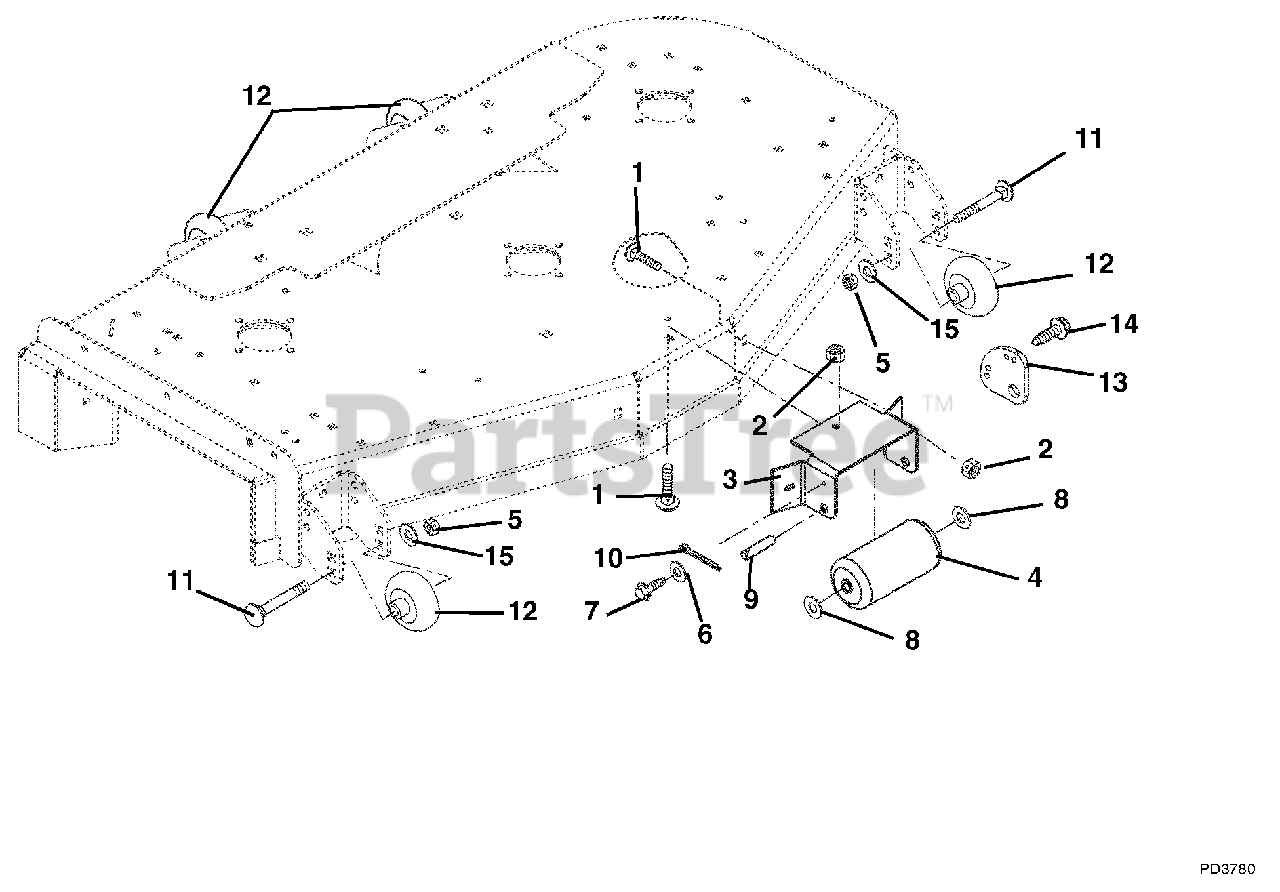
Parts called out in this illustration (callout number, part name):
1	Bolt-Round Head Square Neck .38-16 x 1.00 Grade 5 (042, 043, 044, 054, 310, 311)
1	Bolt-Round Head Square Neck .38-16 x 1.25 Grade 2 (051, 055)
2	Nut-Locking-Top-Flange .38-16
3	Bracket- Anti-Scalp Roller (042, 310)
3	Bracket- Anti-Scalp Roller (043, 044, 054, 311)
3	Bracket, Anti-Scalp Roller (051, 055)
5	Nut-Locking-Nylon .50-13
6	Washer-Flat-Steel .281 x .62 x .065
7	Screw-Tapping .25-20 x .75 Hex Washer Head
8	Washer-Flat-Steel .656 x 1.31 x .095
10	Pin-Cotter .25 x 2.0
11	Bolt-Round Head Square Neck .50-13 x 5.00 Grade 2
12	Wheel, 3 x 5
13	Anti-Scalp Washer
14	Screw-Tapping .25-20 x .62 Hex Washer Head
15	Washer-Flat-Steel .531 x 1.06 x .095
